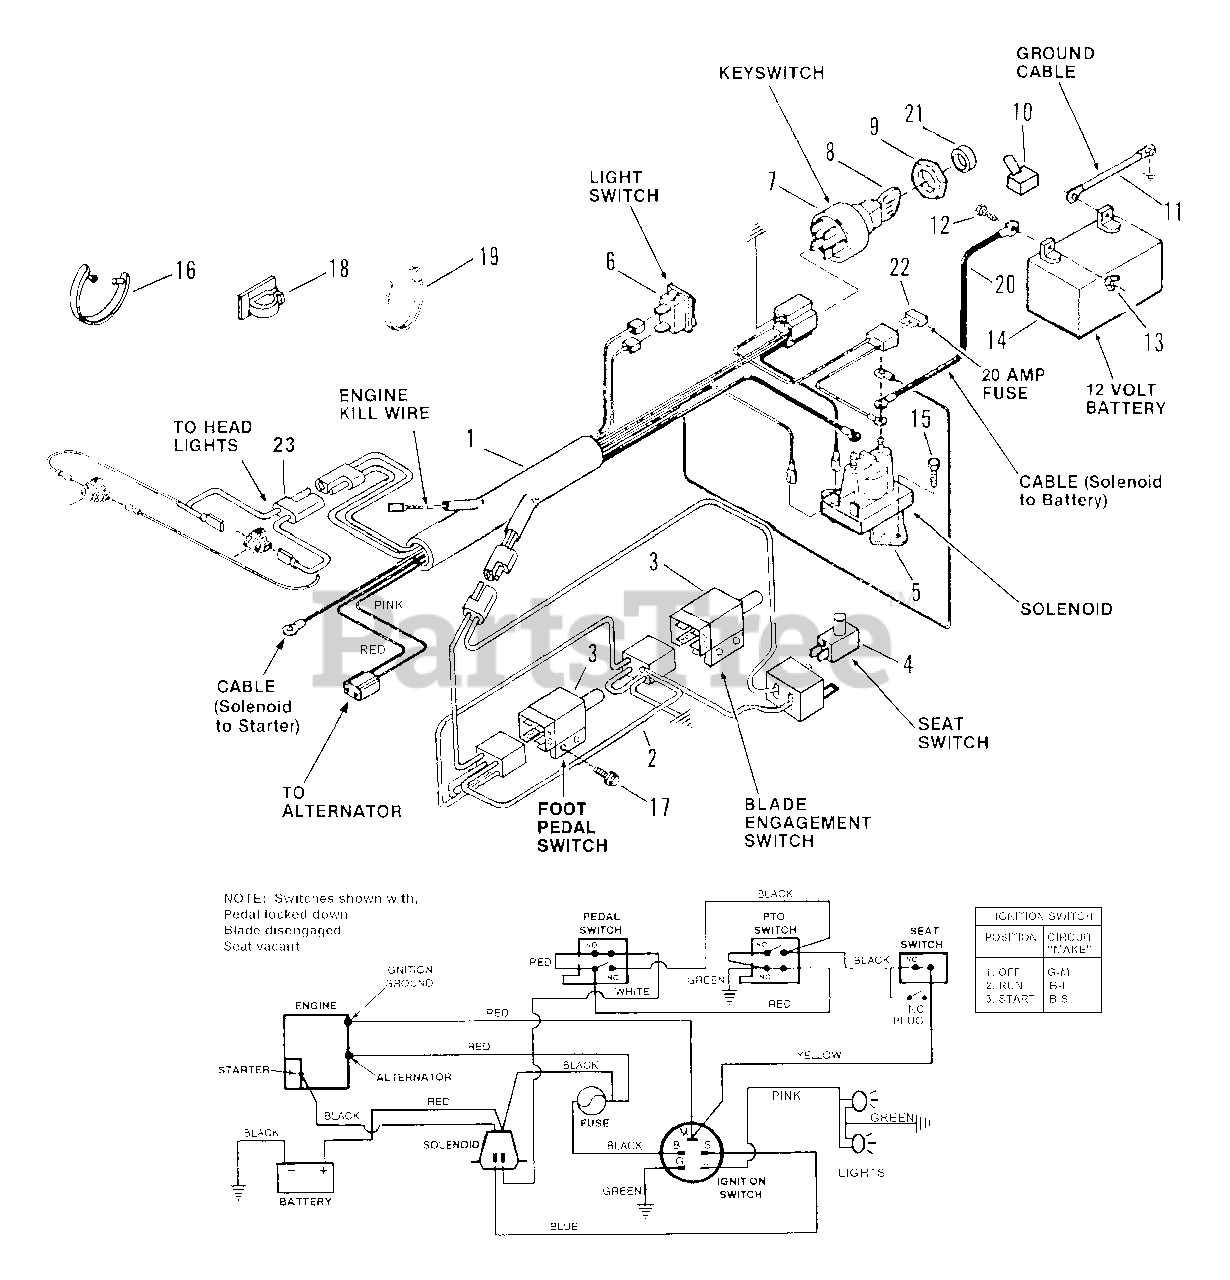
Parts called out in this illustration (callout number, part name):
1	HARNESS, Wiring (B.&S.)
2	HARNESS, Interlock
3	SWITCH, Clutch & PTO
4	SWITCH, Seat NC
5	SOLENOID
6	SWITCH, Light
7	SWITCH, Ignition
8	KEY, Ignition Indak (Set of 2) One Coated
9	NUT, 5/8-32 Hex
10	COVER, Positive Terminal
11	CABLE, Negative 15"
12	BOLT, 1/4-20x3/4" Carriage
13	WING NUT, 1/4-20
14	KIT, Battery
15	SCREW, 1/4-20x1/2" Self-Tapping
16	TIE, Wire
17	SCREW, #10-24 x 1/2" Hex Washer Self-Tap (Torx)
18	CLIP
19	TIE, Cable 7"
20	CABLE, Positive 11"
21	BEZEL
22	FUSE, 20 Amp
23	HARNESS, Head Light Wiring
